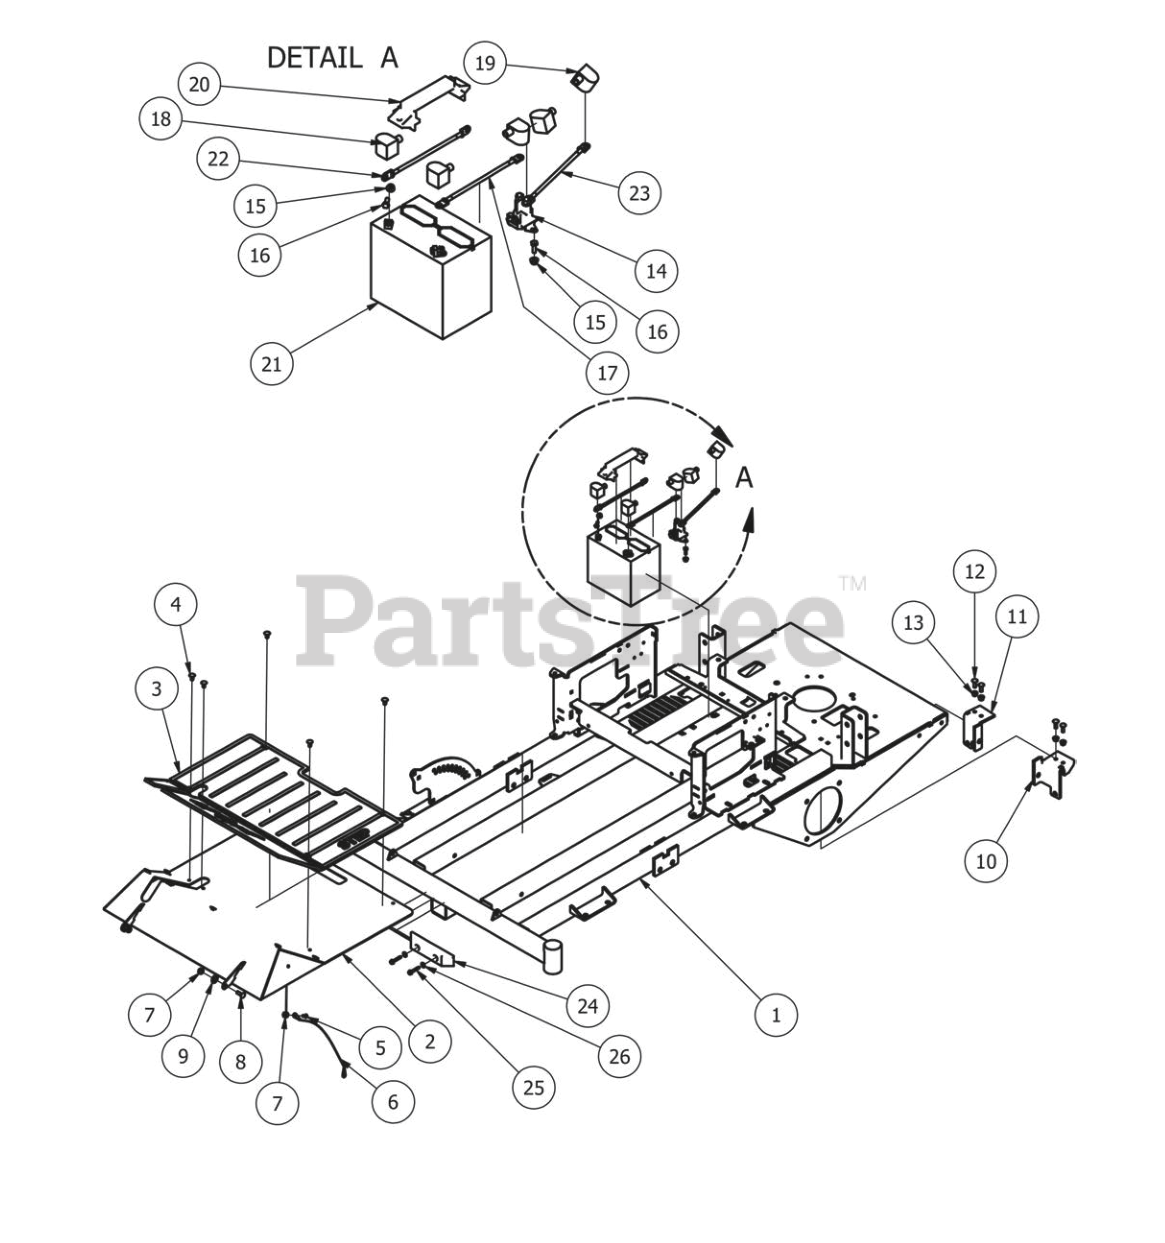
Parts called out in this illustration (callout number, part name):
1	Outlaw Frame
2	Outlaw Floor Panel
3	Foot Assist Floor Mat
4	Ratchet Fastener
5	1/4" x 5/8" BS C/S 18-8 SS
6	Floor board Cable W/ Swivel Ends
7	5/16-18 Nylon Flange Nut
8	5/16" x 1" Carriage Bolt
9	.360 ID Plastic Washer
10	Outlaw Brake Cable Mount Bracket (Right)
11	Outlaw Brake Cable Mounting Bracket (left)
12	5/16" x 1" Carriage Bolt
13	5/16" Flange Nut Zinc W/Serrations
15	1/4-20 Hex Flange Nuts Zinc w/Serrations
16	1/4-20 x 3/4 GR 5 Hex Bolts Zinc
17	24" red battery cable
18	Black Boot For ground cable
20	Hold Down Assembly
22	Starter to chassis cable
23	Red battery cable alternator to Started cable
24	8" Rubber Bumper
25	1/4" x 1 1/2" Self Tapping Screw
26	1/4" Flat Washer
